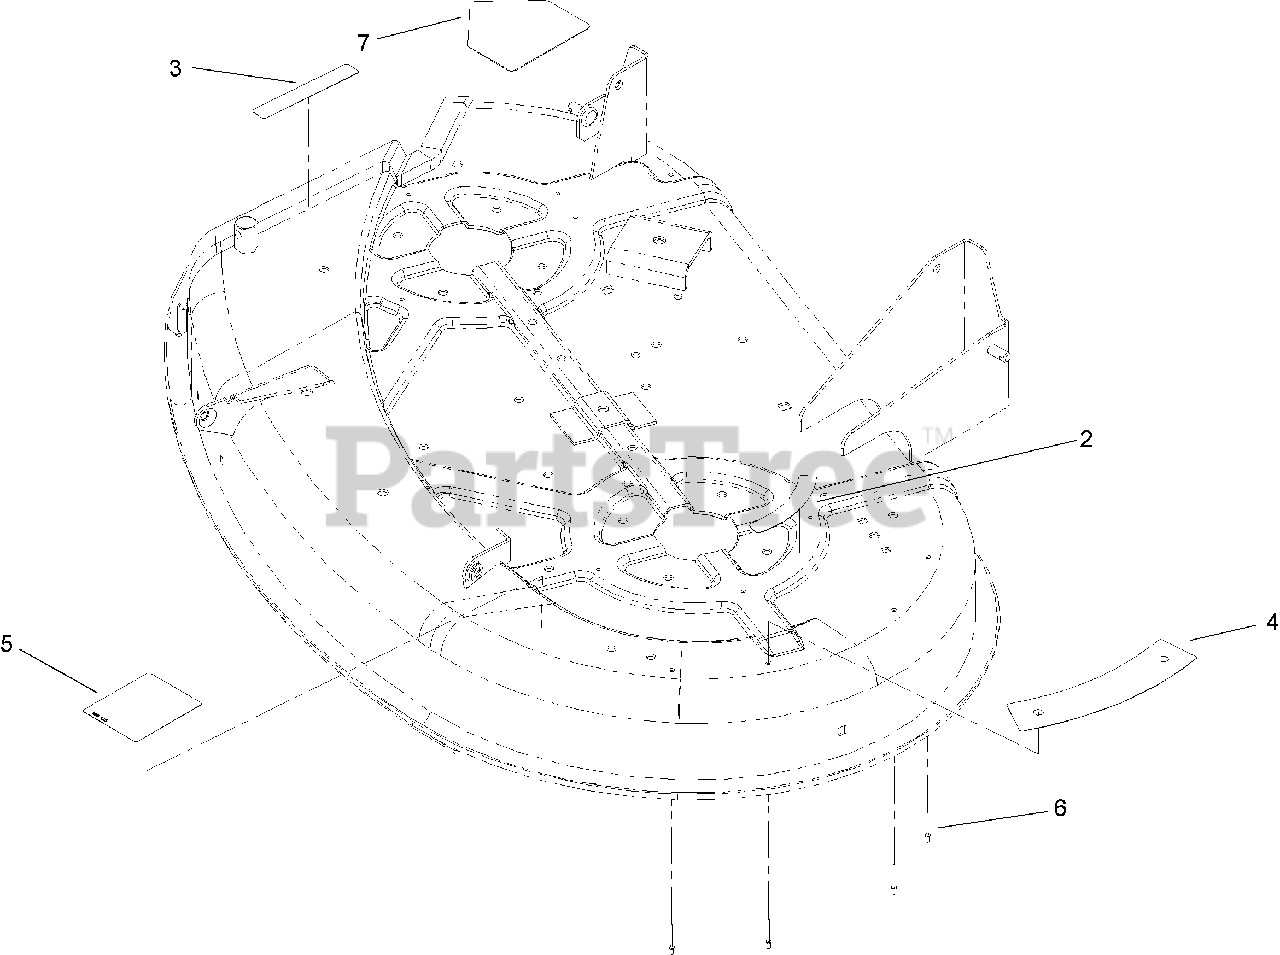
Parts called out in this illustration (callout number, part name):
2	DECAL-DANGER, SHIELD
3	DECAL-DANGER, DEFLECTOR
4	DECAL-DANGER
5	DECAL-ROUTING, BELT
6	RIVET-POP
7	DECAL-DANGER
